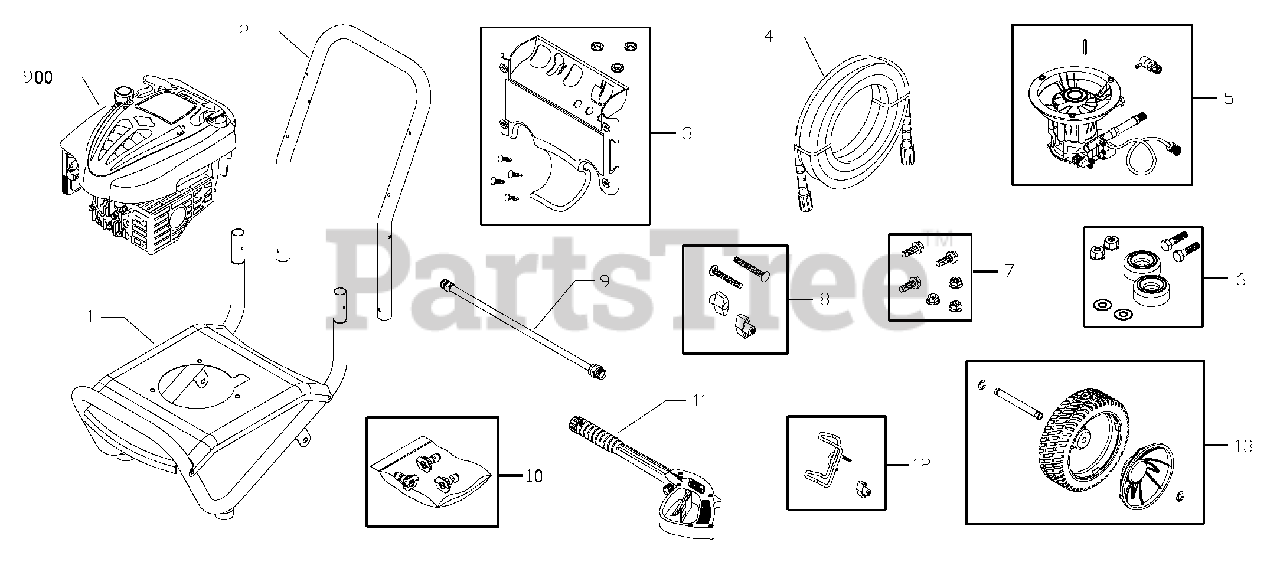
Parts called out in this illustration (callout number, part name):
2	HANDLE
3	KIT, Billboard with Clips
4	HOSE, 25'
6	KIT, Vibration Mount
7	KIT, Pump Mounting Hardware
8	KIT, Handle Connector
9	EXTENSION
11	GUN
12	KIT, Gun Holder
13	KIT, Wheel
900	ENGINE
